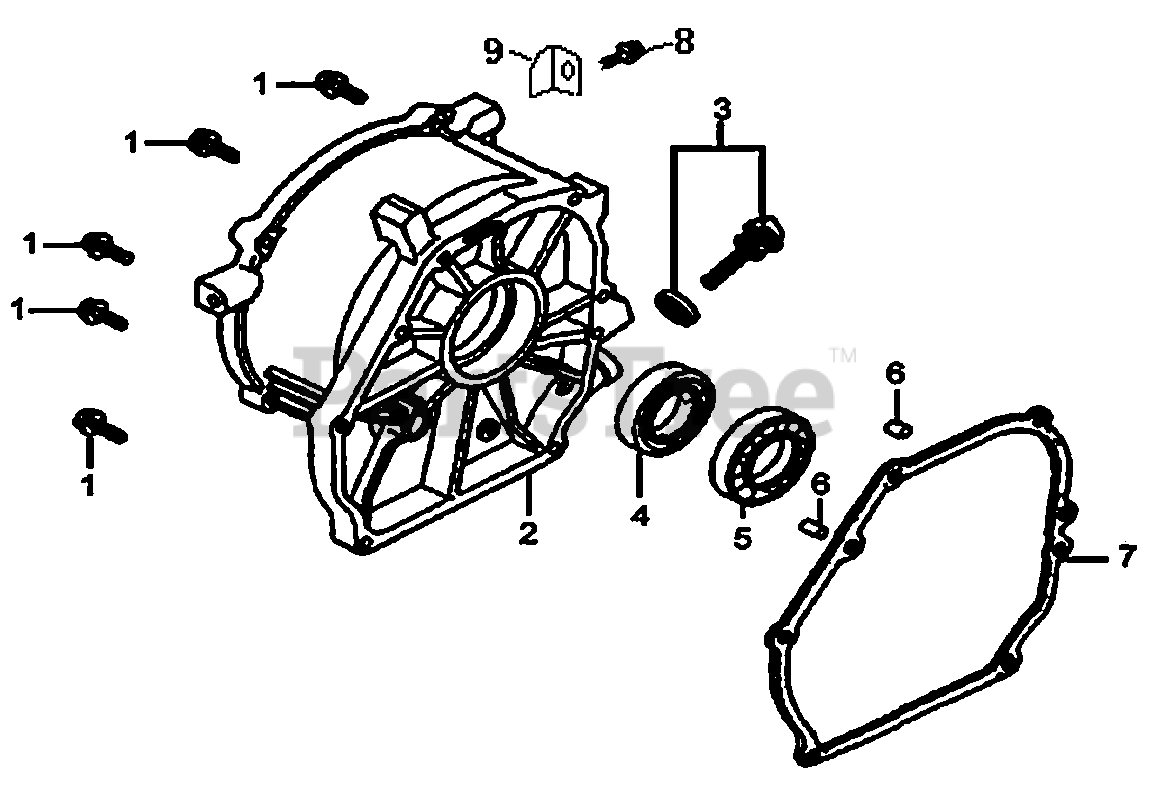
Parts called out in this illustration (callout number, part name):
1	BOLT, FLANGE
2	CASE COVER
3	OIL SWITCH
6	PIN, DOWEL
7	GASKET, CASE COVER
8	BOLT, FLANGE
